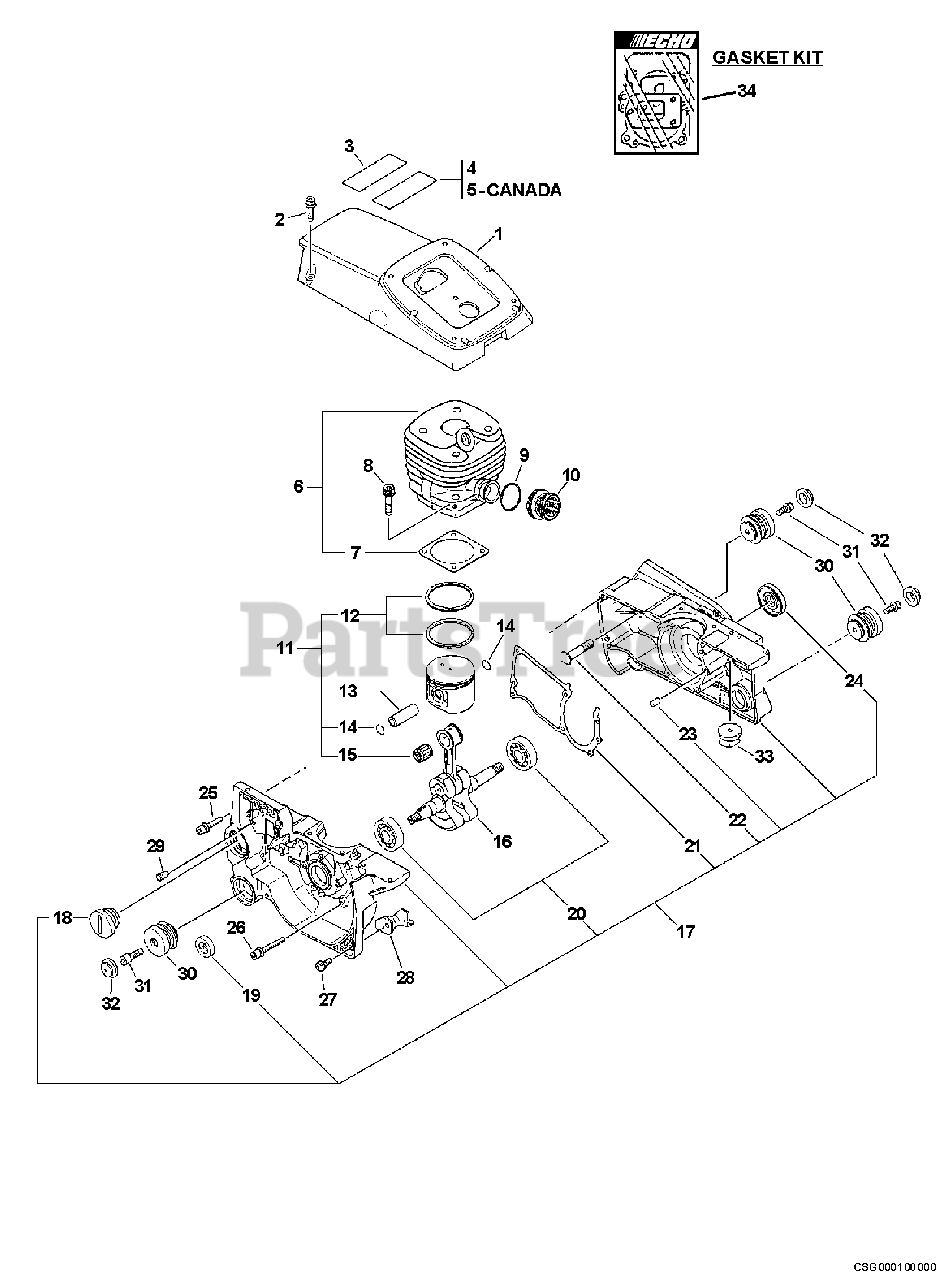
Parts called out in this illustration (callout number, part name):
1	COVER, CYLINDER
2	BOLT 5×20
3	LABEL, CAUTION
4	LABEL, CAUTION
5	LABEL, CAUTION
6	CYLINDER KIT
7	GASKET, CYLINDER
8	BOLT 5×20
9	BAND
10	ADAPTOR, INTAKE
11	PISTON KIT
12	RING, PISTON
13	PIN, PISTON
14	RING, SNAP
15	BEARING, NEEDLE
16	CRANKSHAFT ASSY
17	CRANKCASE KIT
18	CAP, OIL TANK
19	SEAL, OIL
20	BEARING, BALL 6202
21	GASKET, CRANKCASE
23	PIN, LOCATING 5×10
24	SEAL, OIL
25	BOLT 5×20
26	BOLT M5×35
27	SCREW 5×14
29	VENT ASSY
31	BOLT 5×14
32	CAP, CUSHION
34	GASKET KIT
